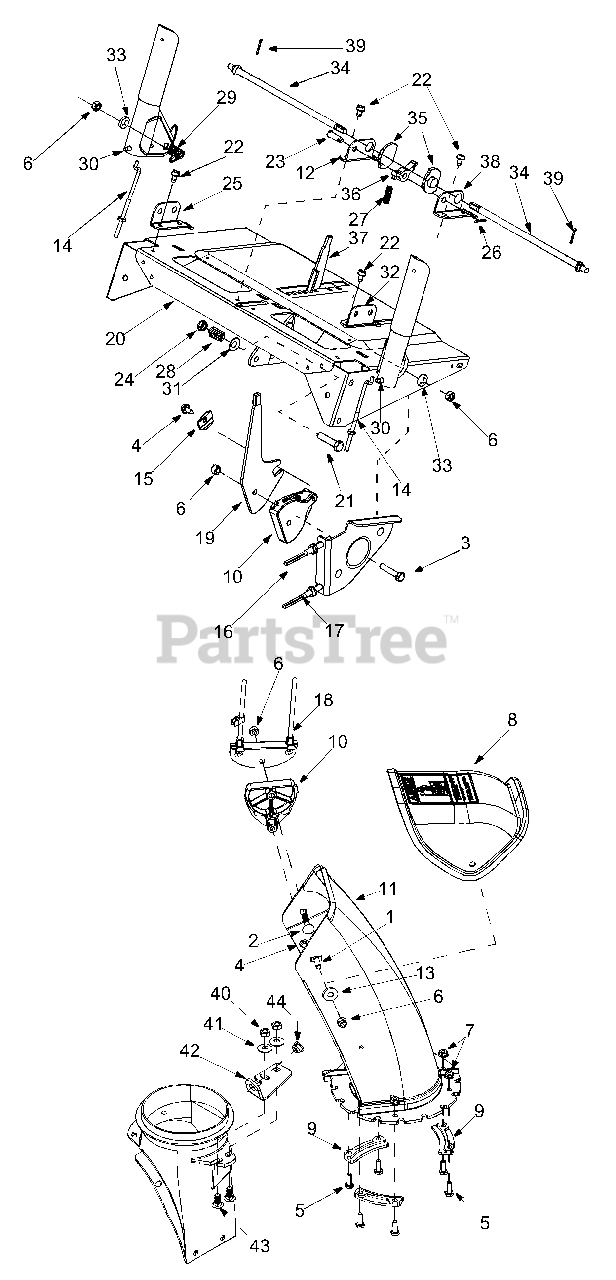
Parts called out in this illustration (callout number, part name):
1	Carriage Bolt 5/16-18 x 1.0"
2	Carriage Bolt 5/16-18 x 1.5"
3	Hex Bolt 5/16-18 x 1.5"
4	Hex AB Screw 1/4-14 x.625"
5	Hex Screw 1/4-20 x.75"
6	Hex Lock Nut
7	Hex Flange Lock Nut
8	Upper Chute
9	Chute Flange Keeper
10	Cable Guide: Chute Tilt
11	Lower Chute
13	5/16 Washer
14	Z Cable Fitting
15	Special Washer
16	Chute Control Cable
17	Chute Cable w/Clip
21	Hex Bolt 3/8-24 x 1.5"
22	TT Screw 1/4-20 x 0.5"
23	Clevis Pin
26	Cotter Pin
29	Torsion Spring
30	Rubber Bumper
31	Bell Washer
33	Special Washer
35	Cam: Handle Lock
36	Pawl: Handle Lock
39	Hairpin Clip
40	Hex Nut 5/16-18
41	Bell Washer
43	Carriage Bolt 5/16-18 x.750"
44	Plastic Bushing
